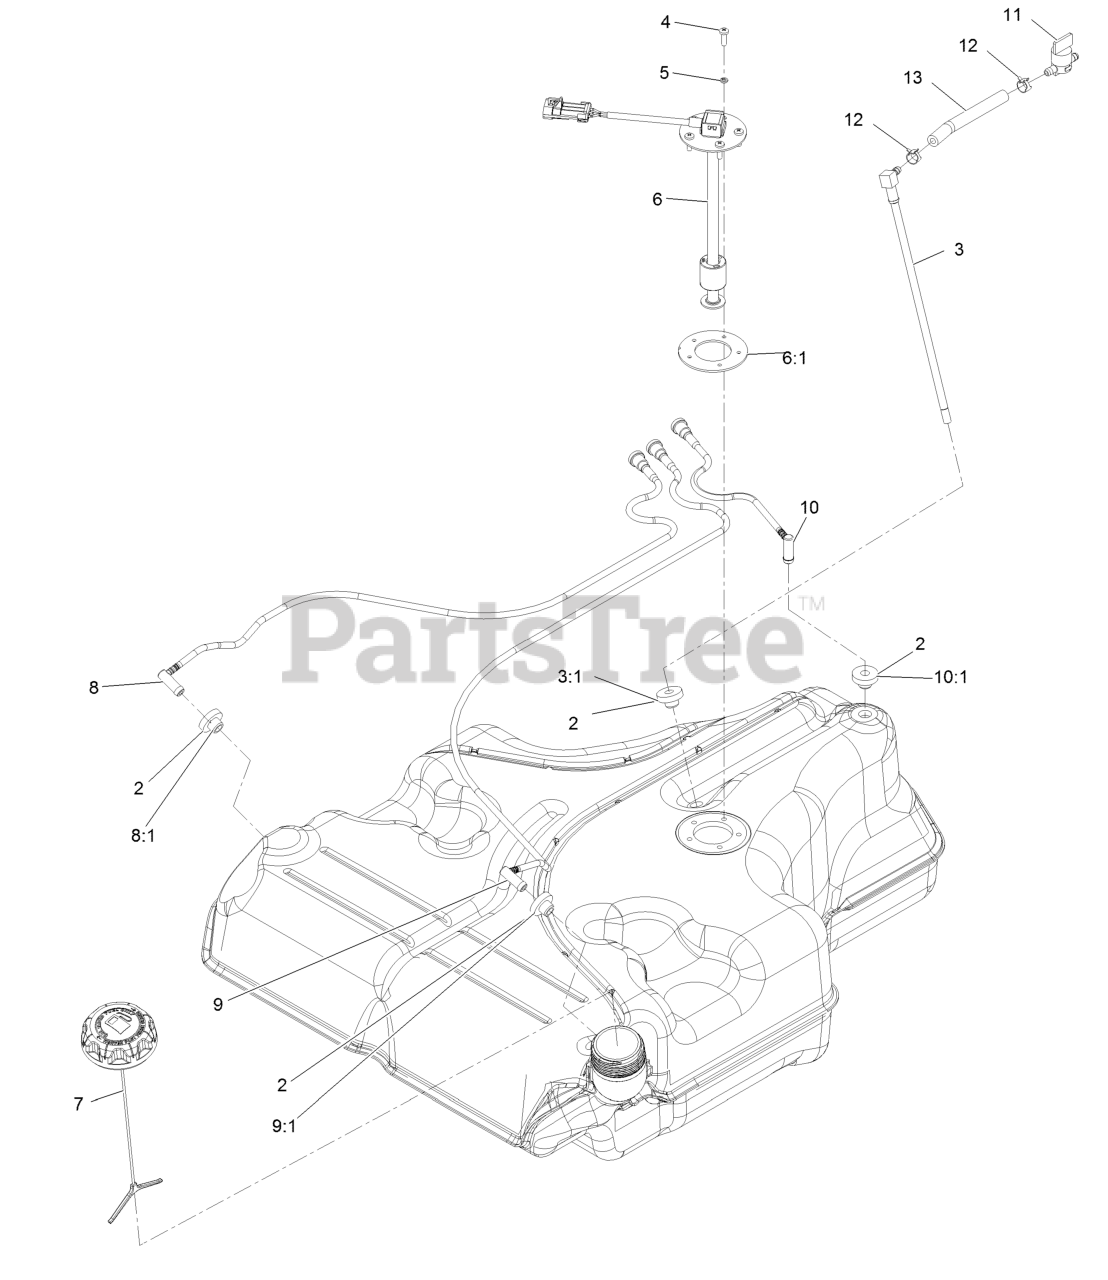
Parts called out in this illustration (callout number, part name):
2	Bushing
3	Fuel Line Kit (With Grommet)
3:1	Bushing
4	Screw-PPH
5	Washer-Lock
6	Float-Sender, Fuel
6:1	Gasket-Sender
7	Cap-Fuel, Ratcheting
8	RH Vent Line Kit (With Grommet)
8:1	Bushing
9	LH Vent Line Kit (With Grommet)
9:1	Bushing
10	Rear Vent Line Kit (With Grommet)
10:1	Bushing
11	Valve-Fuel
12	Clamp-Hose
13	Hose-Fuel
